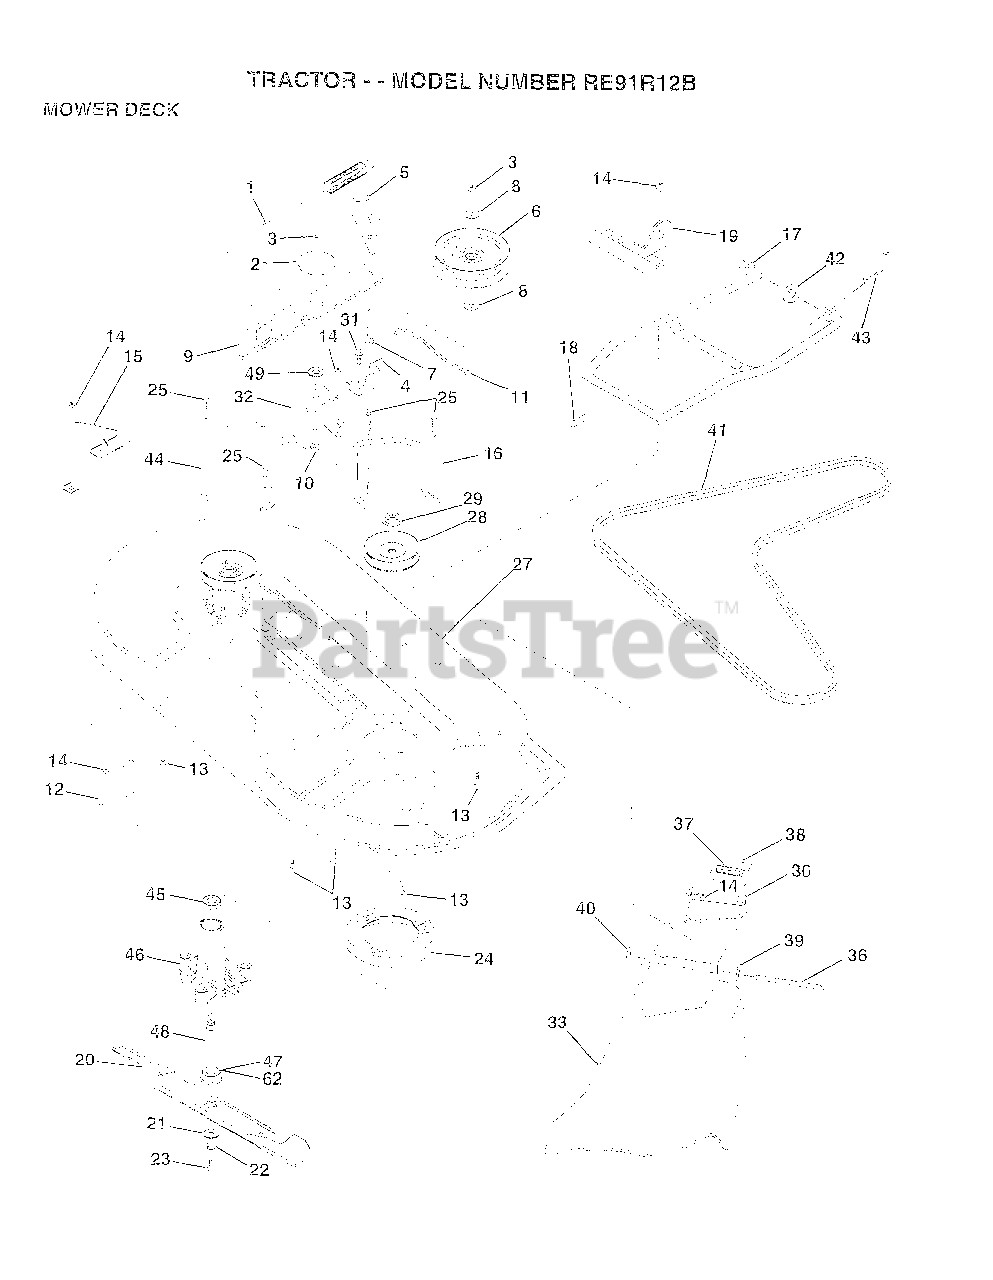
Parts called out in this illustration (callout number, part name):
1	SPRING CLUTCH MWR
2	SPACER RETAINER
4	BRAKE ASM
5	IDLER BELT GUIDE
6	PULLEY IDLER
7	BOLT
8	WASHER
10	BOLT.3/8-14X1.25
11	BRAKE ROD
12	"BRKT,LIFT REAR"
13	BOLT
15	"BRKT,LIFT REAR LH"
16	"KEEPER-BELT,RH"
17	MOWER LINK STAB
18	"PIN,GROOVE"
19	"BRKT,LINK STABILI"
20	"BLADE.36"" HIPERF"
21	WASHER.HARD.BLADE
23	BLADE BOLT
24	STRIPPER RND MWR
25	"SCREW-THD ROLL,WA"
27	"HOUSING-MOWER,36"""
28	PULLEY.MAND.36/46
31	SCREW LT
32	"SUPT,IDLER ARM"
36	HINGE ROD
37	SPRING TORSION
38	CAP-SLEEVE LT
39	WASHER
41	V-BELT.PRIM.78.5.
43	RETAINER.SPRING
44	KEEPER BELT LH
45	BEARING
46	HSG ASM MANDREL
47	BEARING.BALL
49	HARDENED WASHER
62	WASHER.FELT.
